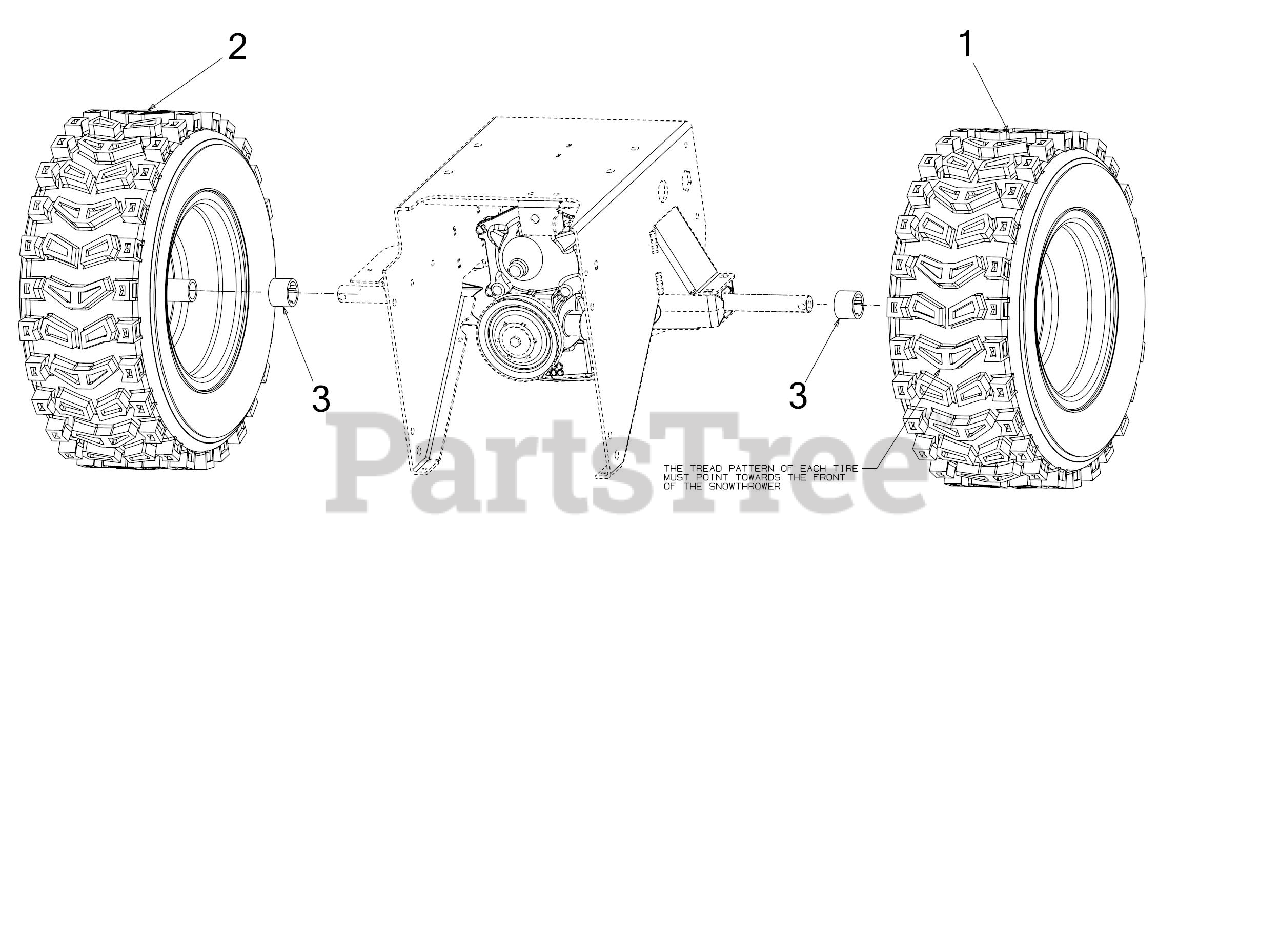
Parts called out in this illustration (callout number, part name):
1	WHEEL ASSEMBLY (16 x 6.5 x 8) (LH)
2	WHEEL ASSEMBLY (16 x 6.5 x 8) (RH)
3	SPACER 1.25 X .75 X .906
